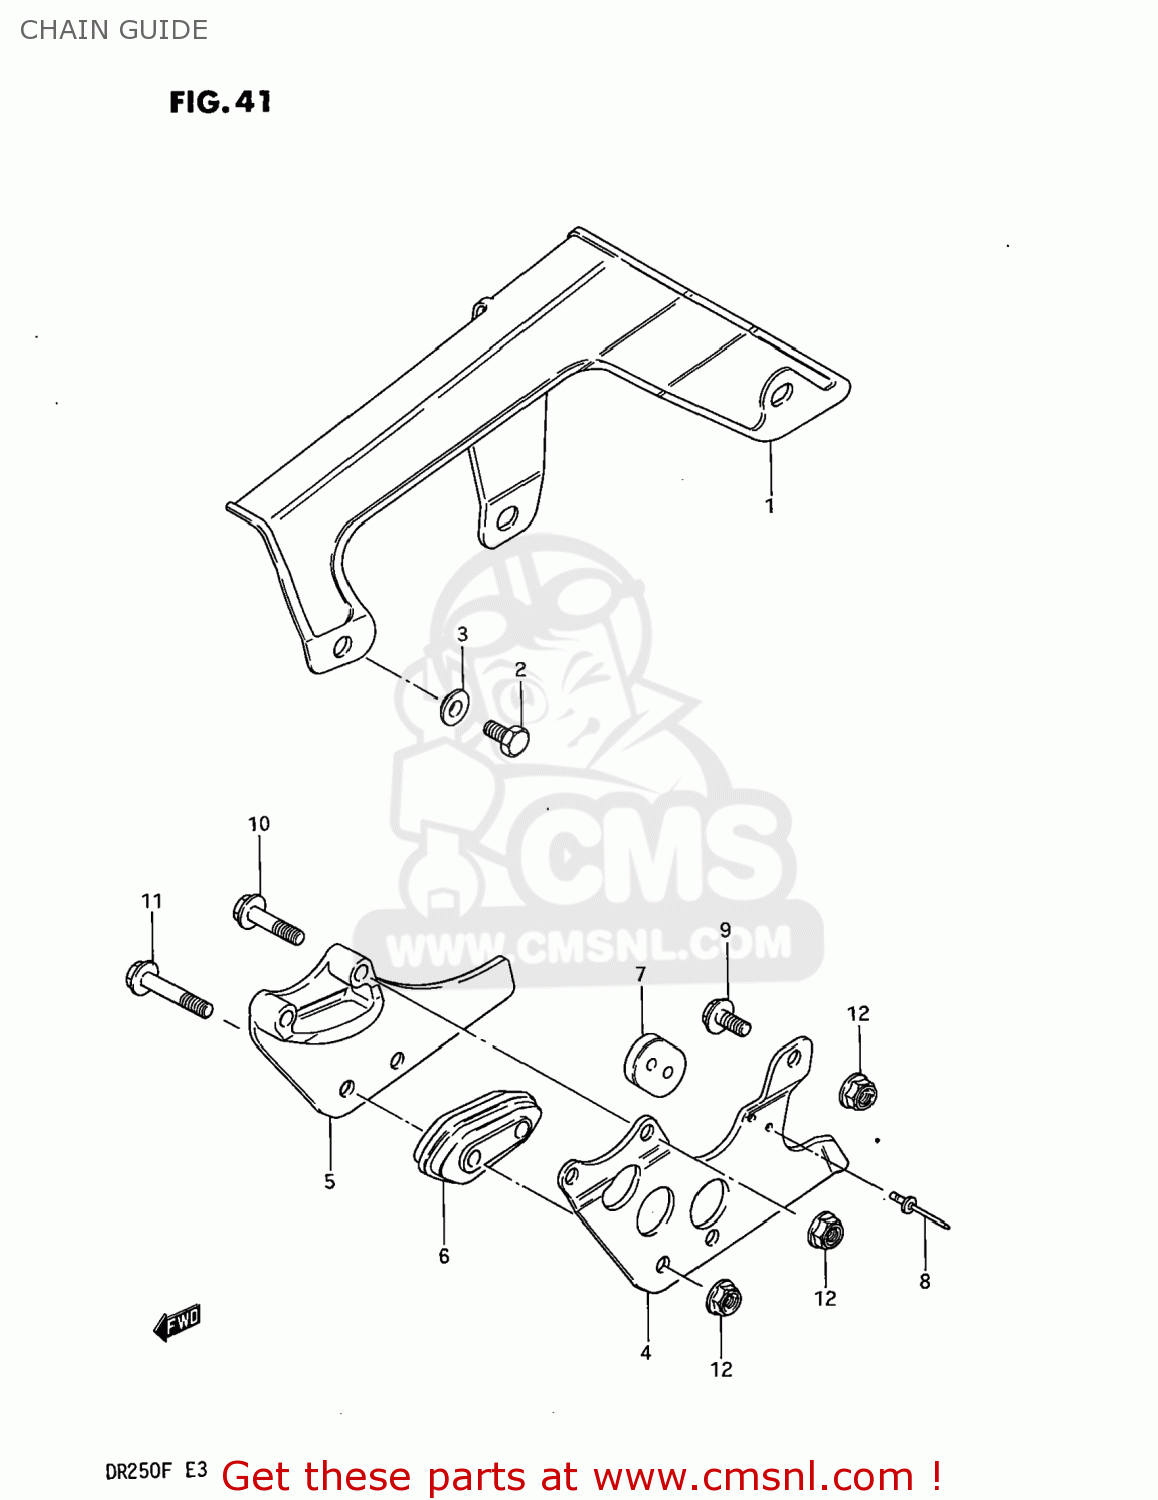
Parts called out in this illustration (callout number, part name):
1	CASE,CHAIN
2	BOLT
3	WASHER,LOCK
4	PLATE,CHAIN GUIDE,OUTER
5	PLATE,CHAIN GUIDE,INNER
6	DEFENSE,CHAIN GUIDE
7	PAD,CHAIN GUIDE
8	RIVET
9	BOLT
10	BOLT 6X35
11	BOLT
12	NUT
